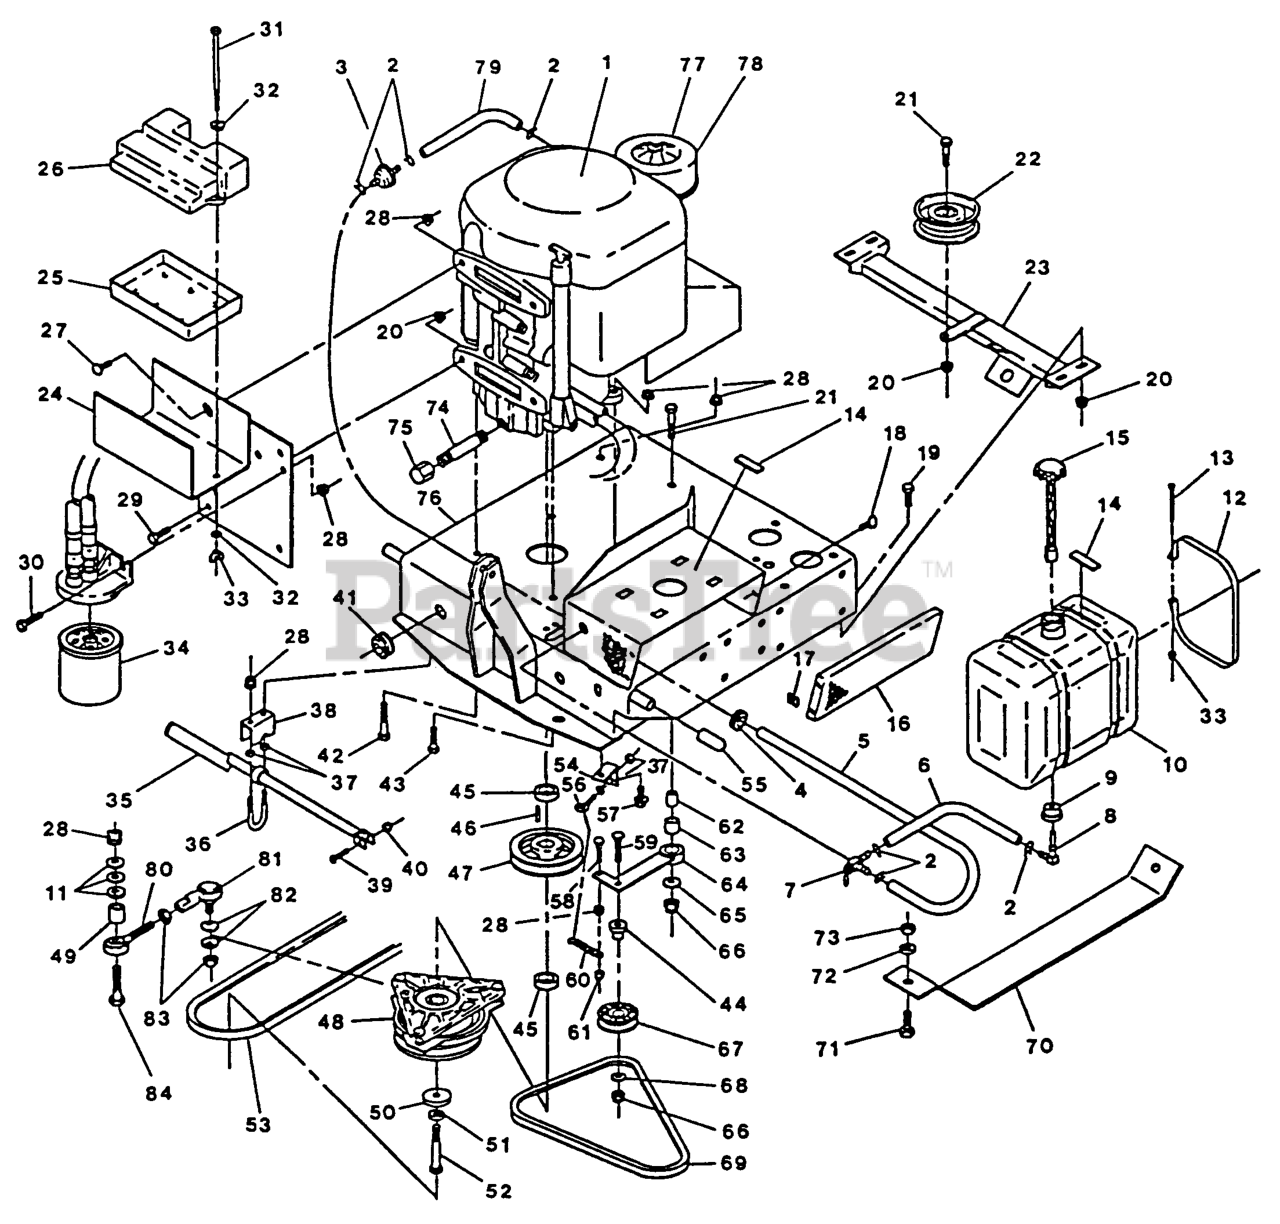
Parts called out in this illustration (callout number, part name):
1	Engine, 18 Hp
4	GROMMET
8	ELBOW-TANK, FUEL
14	PAD,PLASTIC TANK
17	NUT,RETNR UTYP 1/4-20
18	SCREW,REGTHMB,
33	WINGNUT
40	NUT-LOCK, HH
41	GROMMET
50	WASHER-CLUTCH
53	BELT-DK DR FMD-60/TR
55	GRIP-LEVER, DRIVE
56	EYEBOLT-THREAD, RH
62	BUSHING,STEEL
63	BUSHING,IDLER ARM
64	WLD,IDLER ARM HYDRO
69	BELT,A TRANS DRIVE
70	PLATE-SKID
81	BALLJOINT
82	WASHER-SPRING
